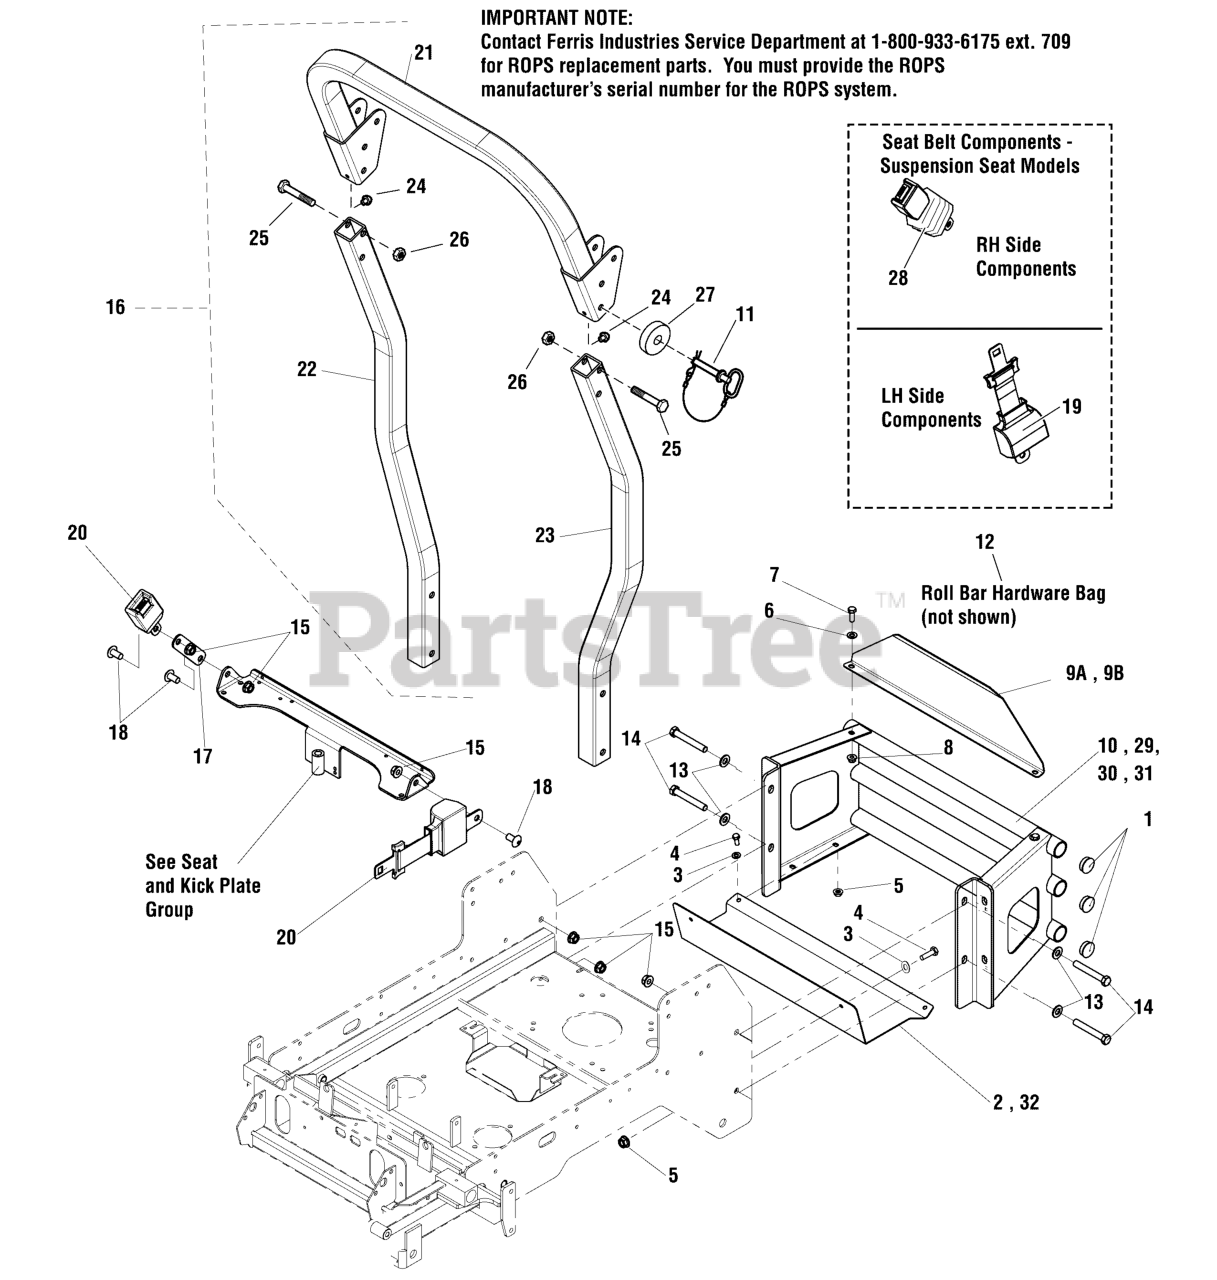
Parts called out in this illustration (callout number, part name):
1	PLUG, PANEL, 1.25 BLACK
2	PLATE, HEAT SHIELD
3	WASHER, 5/16" SAE
4	BOLT, 5/16-18 X 3/4 GD5
5	NUT, 5/16-18 HEX NYLOCK FLANGE
6	WASHER, 3/8 SAE
7	BOLT, 3/8-16 X 1" GD5 CZ
8	NUT, 3/8-16 HEX NYLOCK FLANGE
10	WELD, BUMPER
11	PIN, HITCH, BLACK W/ PLASTIC LANYARD
12	ROLL BAR HARDWARE BAG
13	WASHER, 1/2 SAE
14	BOLT, 1/2-13 X 3-1/4, HEX HD, GD5, CZ (SV)
15	NUT, Hex Flange, Nylock, 1/2-13
16	ROPS (Call 1-800-933-6175 ext. 2193 if replacing a ROPS)
17	EXTENSION, SEAT BELT - BLK
18	SCREW, 1/2 - 13 X 1.00 SCHS
19	ORDER P/N 5105137 (CONTAINS BOTH SEAT BELT RETRACTOR & SUPER SLEEVE BUCKLE)
20	SEAT BELT, RETACTING - ASSM
21	ROLL BAR TOP LOOP
22	ROLL BAR POST, RH
23	ROLL BAR POST, LH
24	RUBBER BUMPER
25	* BOLT
26	* NUT
27	RUBBER WASHER
28	SEAT BELT ASSM, RETRACTOR + SUP SLEEVE
29	WELD, BUMPER - RED
30	WELD, BUMPER
31	WELD, BUMPER, KOHLER, IS2000Z - RED
32	PLATE, HEAT SHIELD, KOHLER, IS2000Z - BLK
